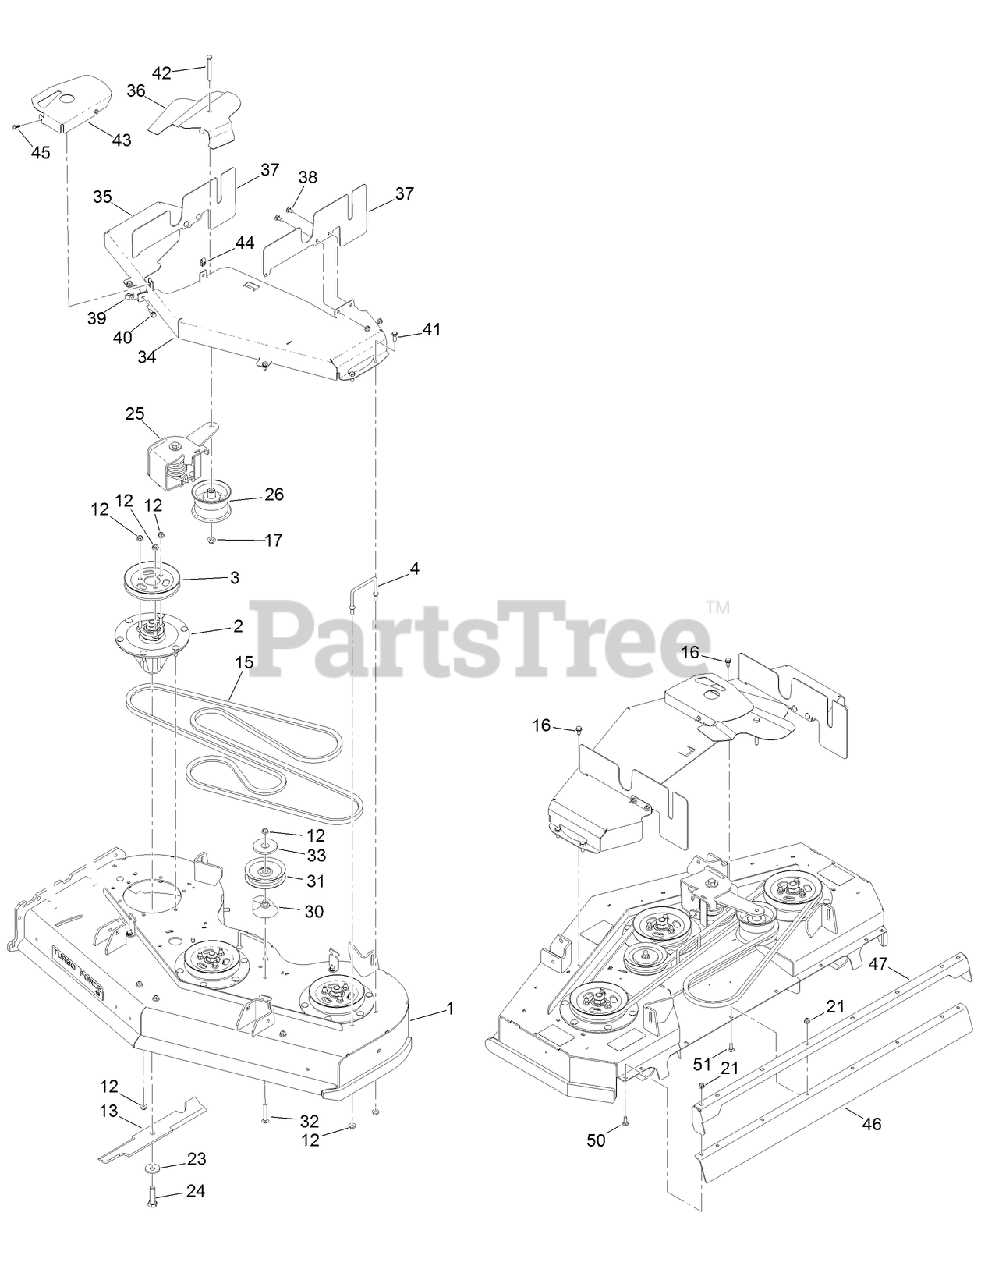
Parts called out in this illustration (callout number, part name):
1	DECK AND DECAL ASM
2	SPINDLE ASM
3	PULLEY
4	WIREFORM-COVER
12	NUT-HF, NI
13	BLADE-ROTARY, 16.5 INCH (ATOMIC)
15	BELT-V
16	SCREW-HWHTF
17	NUT-FLANGE, NI
21	NUT-HF, NI
23	WASHER-BLADE BOLT, HEAVY
24	SCREW-BLADE
25	IDLER TORSION ASM
26	PULLEY-IDLER
30	SPACER-PULLEY
31	PULLEY-IDLER, FLAT
32	SCREW-CARR
33	SHIELD-DUST
34	COVER-BELT, LH, CE
35	COVER-BELT, RH CE
36	COVER-IDLER, CE
37	COVER-SIDE, LH (CE)
38	SCREW-CARR
39	NUT-U
40	SCREW-HHF
41	SCREW-HH
42	SCREW-HH
43	COVER-IDLER, CE
45	SCREW-HHF
46	DEFLECTOR
47	BRACKET-DEFLECTOR
50	SCREW-CARR
51	BOLT-CARR
